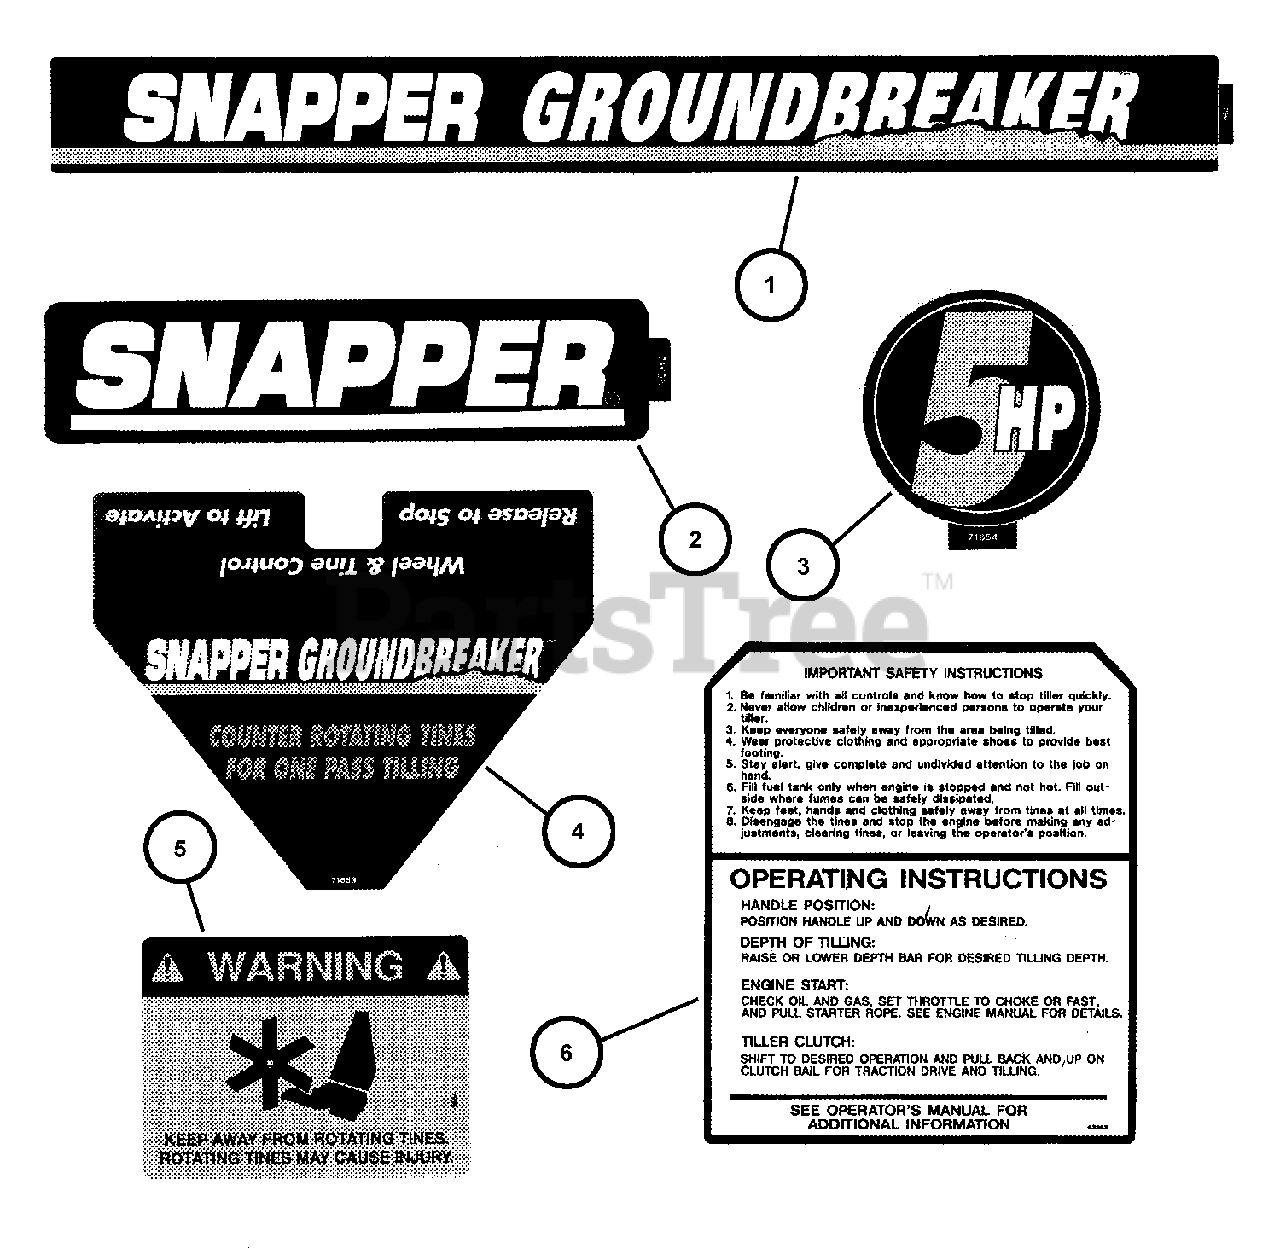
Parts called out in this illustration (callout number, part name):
1	DECAL, Ground Breaker (5HP)
2	DECAL, SNAPPER
3	DECAL, 5HP Engine
4	DECAL, Dash Panel (5HP)
5	DECAL, Warning (Rotating Tines)
6	DECAL, Safety Operating Instructions
